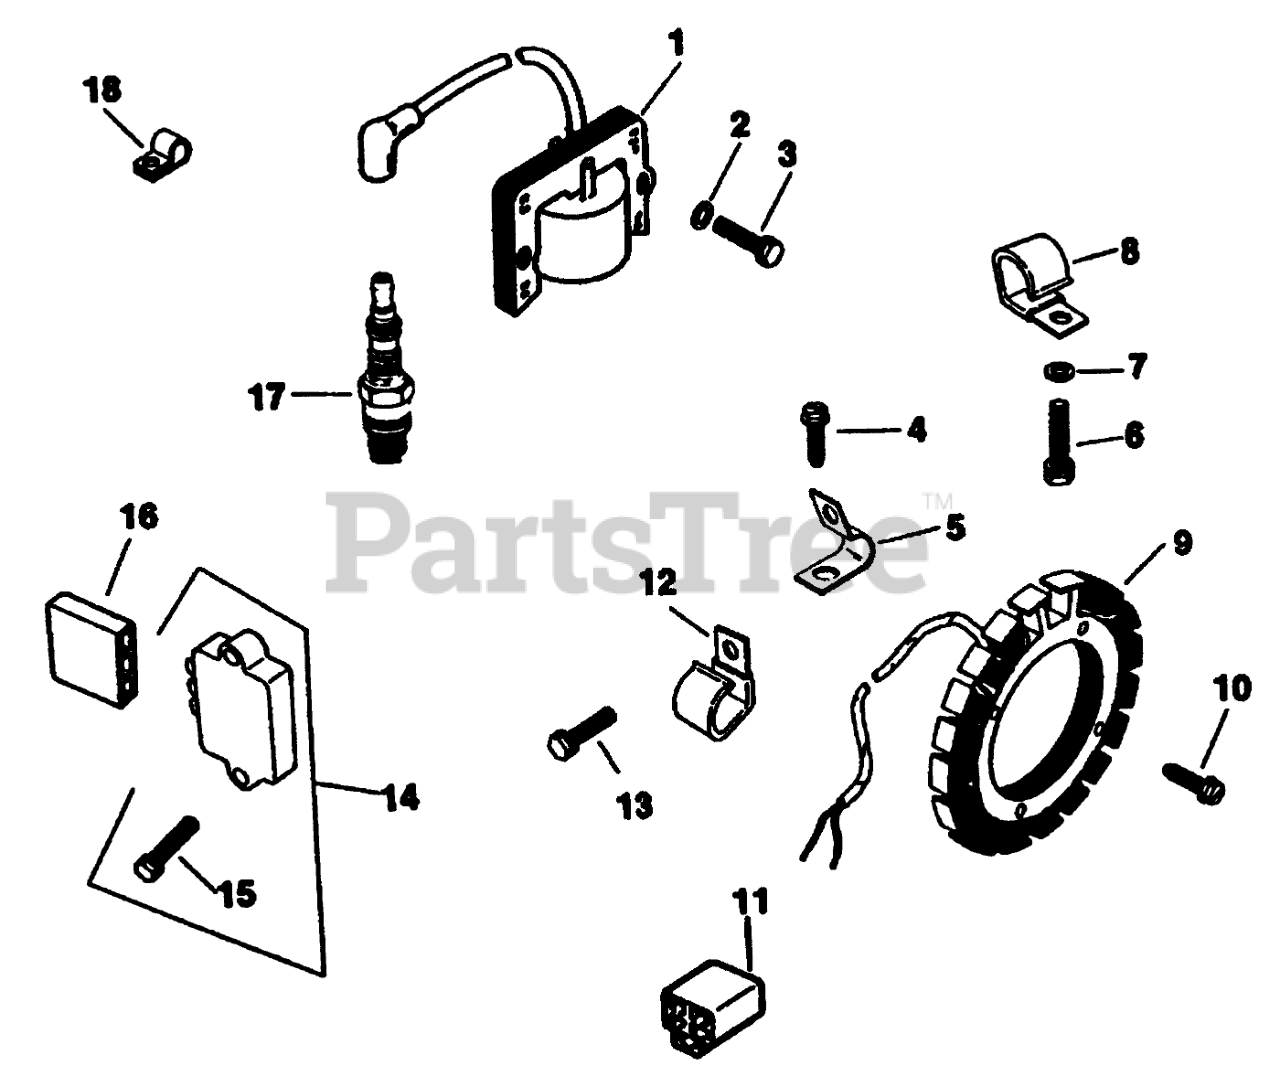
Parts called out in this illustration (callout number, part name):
1	Module-Ignition
2	Washer
3	Screw
4	Screw-Hex. Hd.
6	Screw
7	Washer
8	Clip
9	Kit-Stator 15 amp (Includes Item #8)
10	Screw
11	Connector
12	CLIP
13	SCREW-HH
14	Regulator-Rectifier
15	Screw
16	Connector
17	Plug-Spark
18	Clip-Hi-Tension
